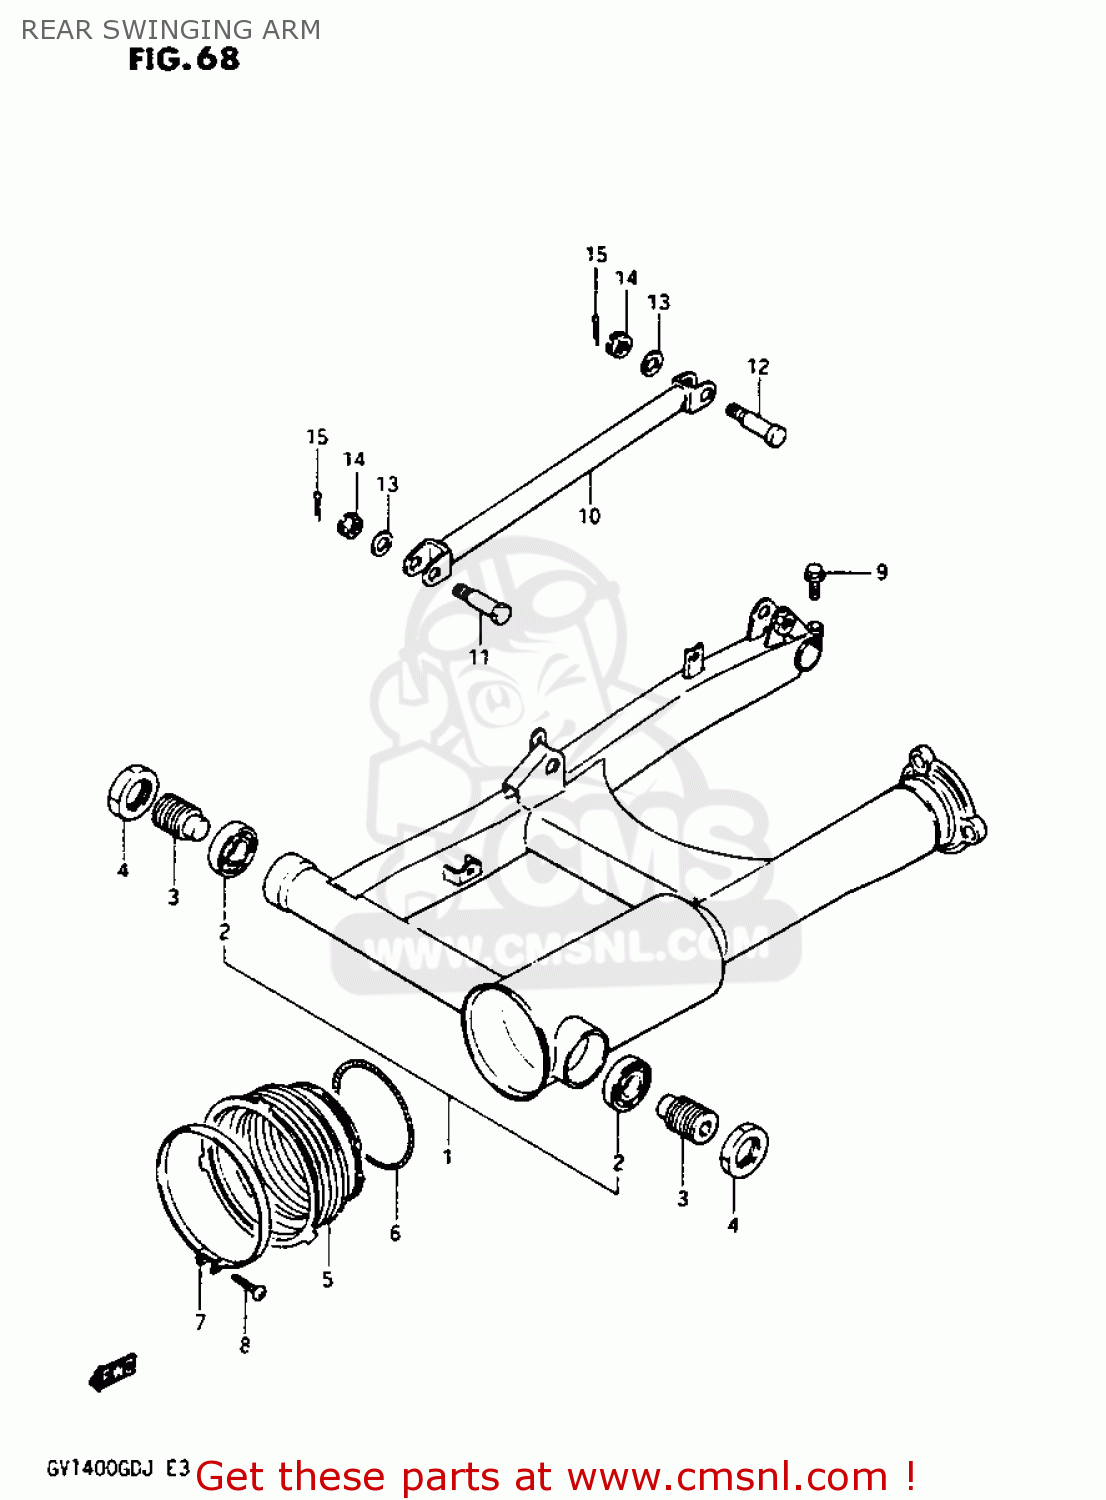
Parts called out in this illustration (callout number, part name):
1	SWING ARM ASSEMBLY,REAR
2	BEARING(17X40X13.25)
3	BOLT,RR SWGARM PIVOT
4	NUT
5	BOOT,PROPELLER SHAFT
6	SPRING,PROPELLER SHAFT
7	CLAMP
8	SCREW 4X25
9	BOLT
10	TORQUE LINK,REAR
11	BOLT
12	BOLT(10X39)
13	WASHER 10MM
14	NUT
15	PIN 20X20
